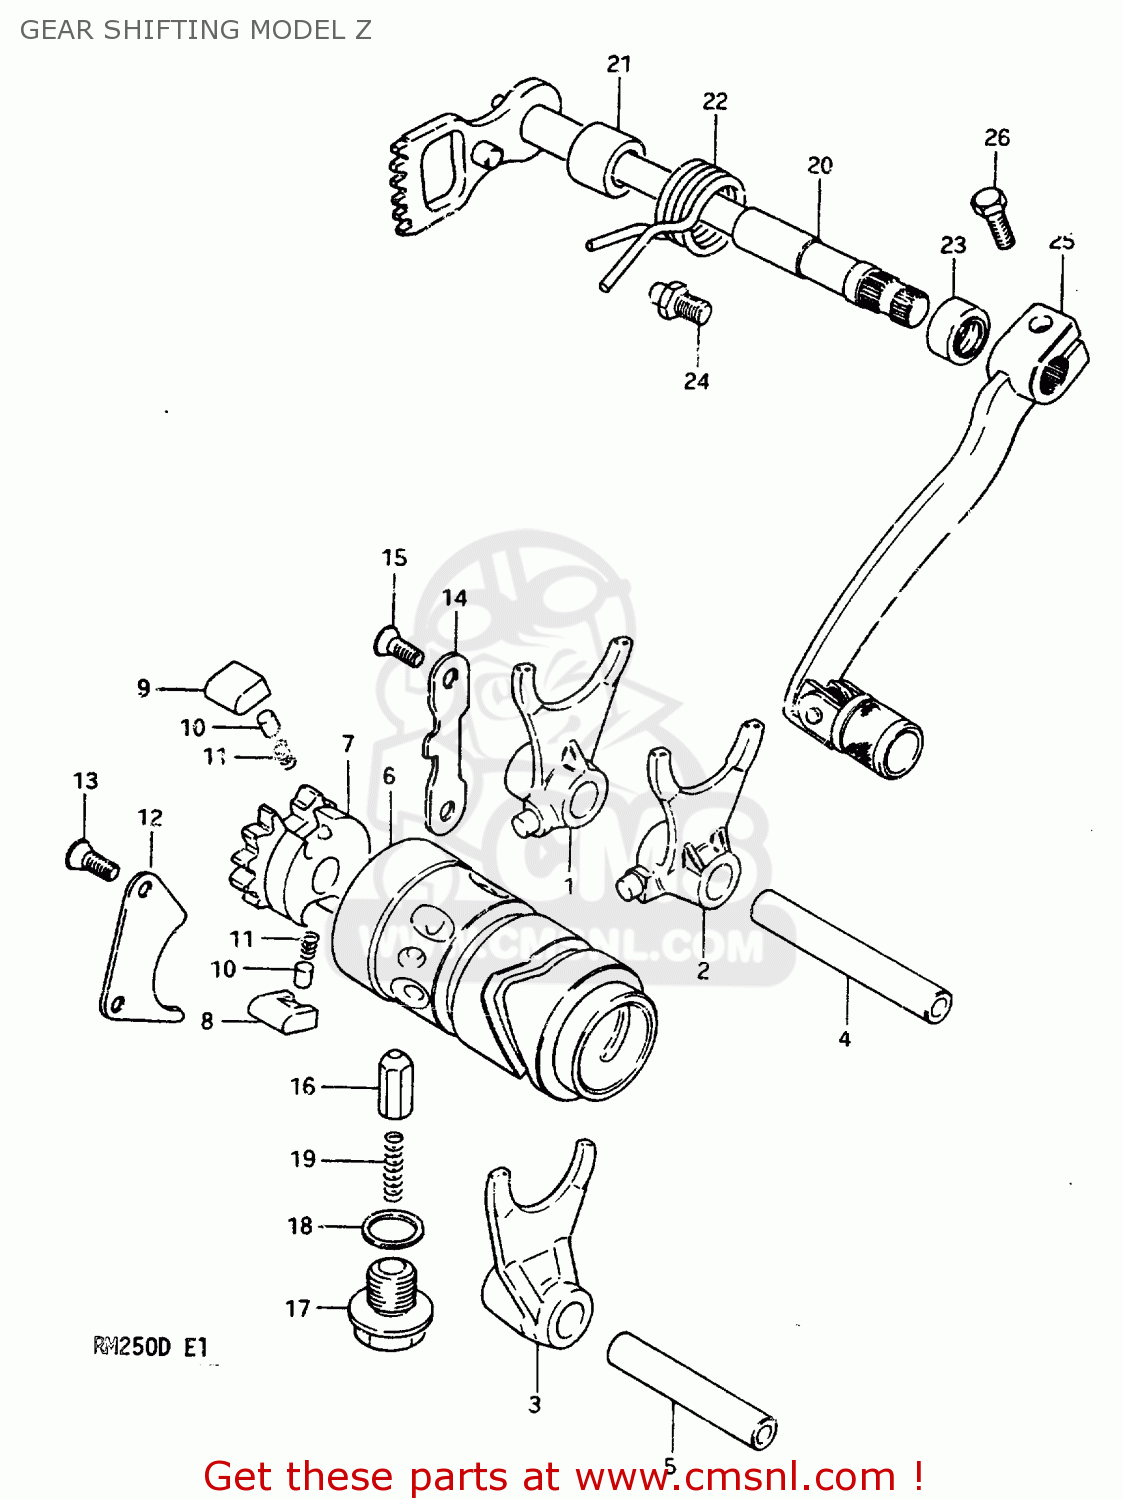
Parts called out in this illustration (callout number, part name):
1	FORK,GEAR SHIFT NO.1
2	FORK,GEAR SHIFT NO.2
3	FORK,GEAR SHIFT NO.3
4	SHAFT,GEAR SHIFT FORK
5	SHAFT,GEAR SHIFT FORK
6	CAM,GEAR SHIFT
7	GEAR,GEARSHIFT CAM DRIVE
8	PAWL,GEAR SHIFT NO.1
9	PAWL,GEAR SHIFT NO.2
10	PIN(5X8)
11	SPRING
12	LIFTER,GEAR SHIFT PAWL
13	SCREW
14	STOPPER,GEAR SHIFT POLE
15	SCREW
16	STOPPER,GEAR SHIFTING
17	BOLT,GEAR SHAFT CAM STOPPER
18	GASKET(14X19.2X2) (NAS)
19	SPRING
20	SHAFT,GEAR SHIFT
21	SPACER(12X20X15.3)
22	SPRING
23	OIL SEAL
24	STOPPER,GEAR SHIFT CAM
25	LEVER ASSEMBLY,GEAR SHIFTING
26	BOLT
